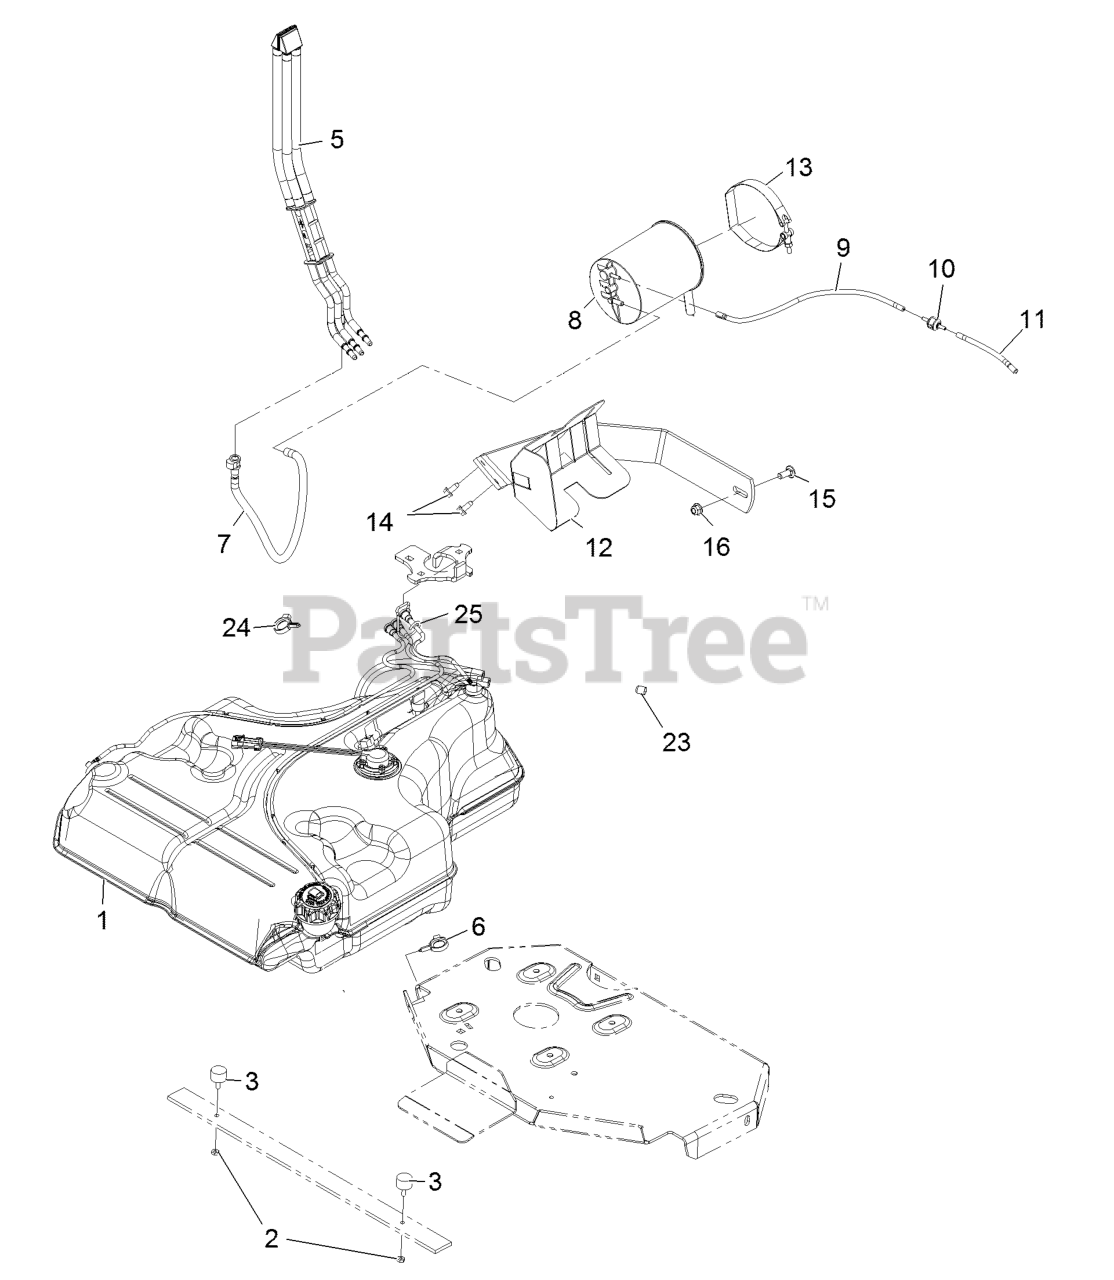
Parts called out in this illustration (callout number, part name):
2	NUT-JAM
5	FUEL MANIFOLD VENT ASM
6	CLAMP-HOSE
7	VENT HOSE ASM
8	CANISTER-CARBON, 1200CC
9	HOSE-VENT, FORMED
11	HOSE-VENT, FORMED
12	MOUNT-CANISTER
13	CLAMP, T-BOLT
14	Screw-HWH 5/16-18 X 3/4 Tf
15	SCREW-CARR
16	NUT-HF, NI
23	PLUG-PORT
24	CLAMP-HOSE
25	RETAINER-LINE, VAPOR
